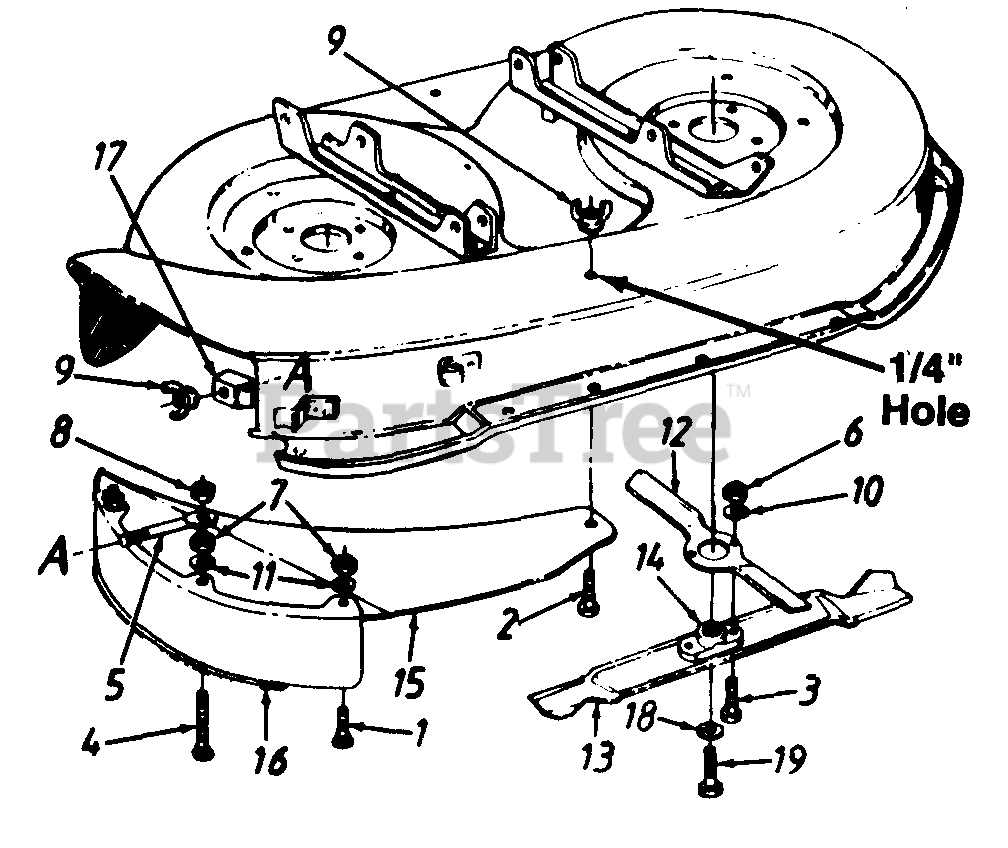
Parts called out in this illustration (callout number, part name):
1	Carriage Bolt 1/4-20 x .62" Lg.
2	Hex Bolt 1/4-20 x .62" Lg.
3	Hex Bolt 7/16-20 x 1.25" Lg. (Gr. 5)
4	Carriage Bolt 1/4-20 x 1" Lg.
5	Retaining Bolt
6	Hex Nut 7/16-20 Thd.
7	Hex Nut 1/4-20 Thd.
8	Hex L-Nut 1/4-20 Thd.
9	Wing Nut
10	L-Wash. 7/16" I.D.
11	L-Wash. 1/4" I.D.
12	Mulching Blade 12.5"
13	Mulching Blade 19.38"
13	Mulching Blade 21.2"
14	Blade Adapter
15	Top Mulching Baffle
16	Side Mulching Baffle
17	Locking Bracket
18	L-Wash. 3/8" I.D.
19	Hex Bolt 3/8-24 x 1" Lg. Gr. 8
